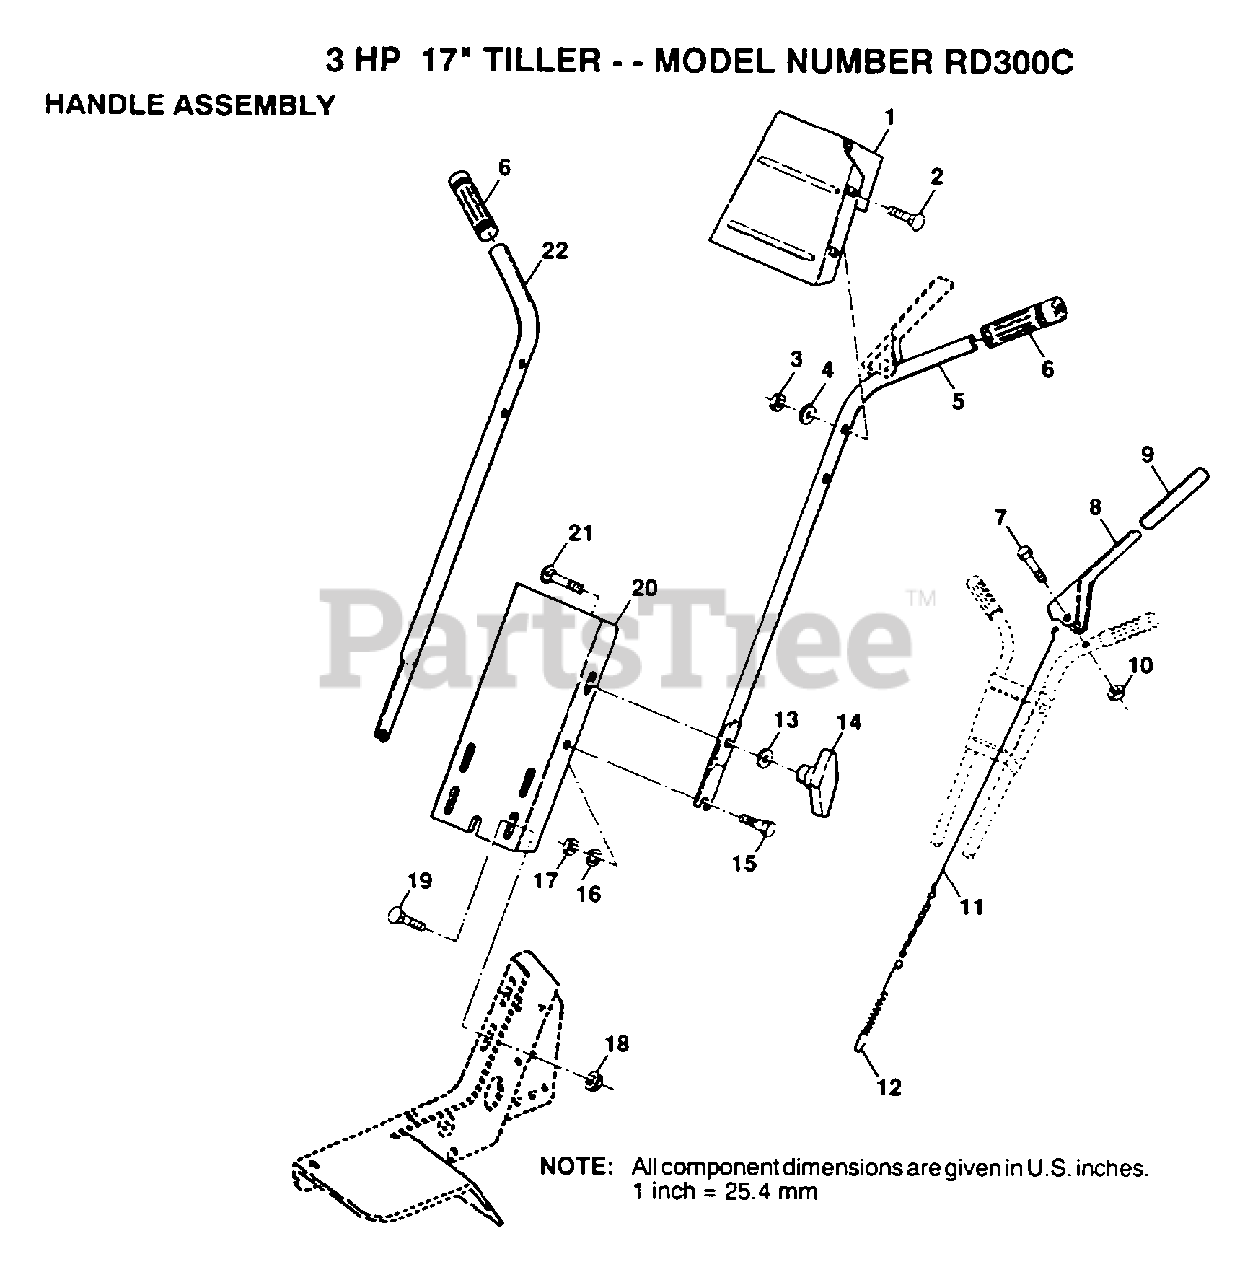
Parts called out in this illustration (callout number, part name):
1	HANDLE BRACKET
2	BOLT
4	WASHER
7	BOLT.HEX.5/16-1.5
9	GRIP T
12	SPRING EXT TI
13	WASHER
16	LOCKWASHER
17	NUT.HEX.5/16-18
18	NUT
19	BOLT
20	"PANEL,HANDLE"
